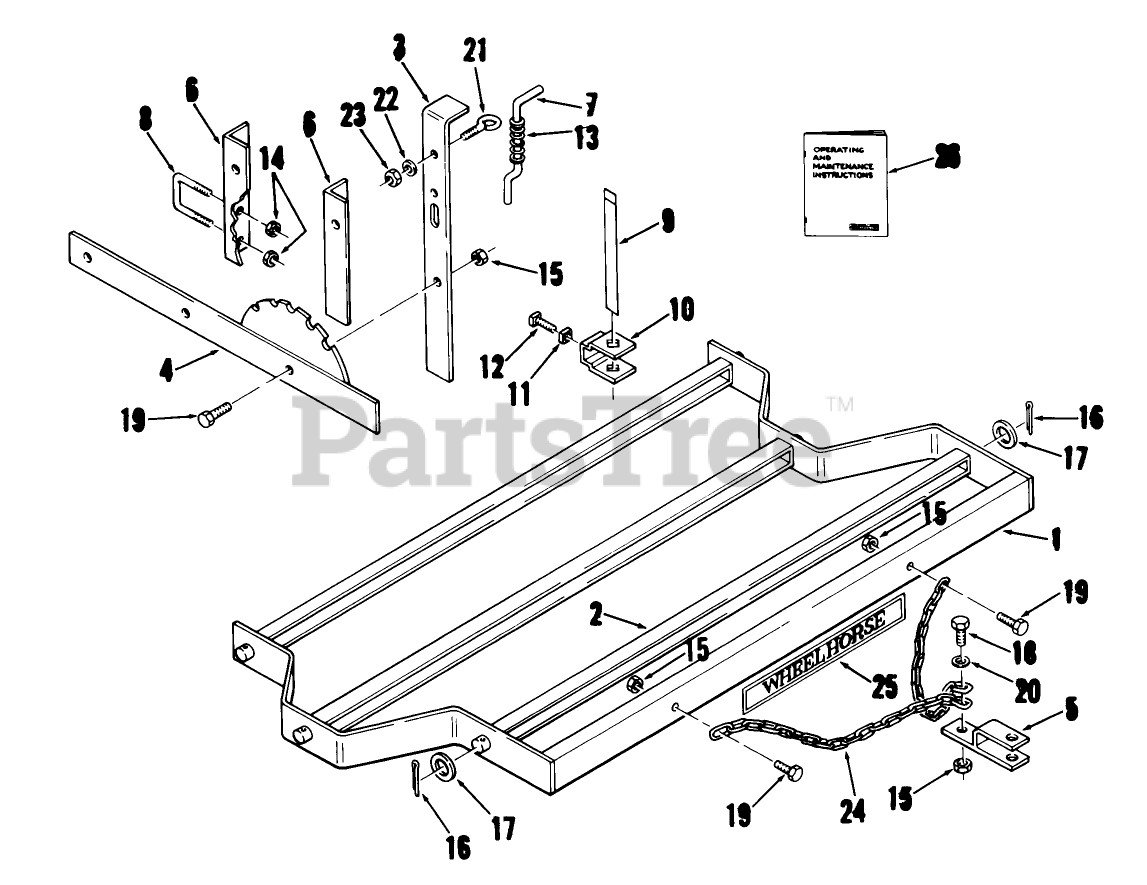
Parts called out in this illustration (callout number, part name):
1	Frame Assembly
3	Handle Assembly
6	Adjusting Angle
7	Locking Pin
8	U Bolt
21	Eyebolt
22	WASHER
24	Chain
26	Operating and Maintenance Instructions
